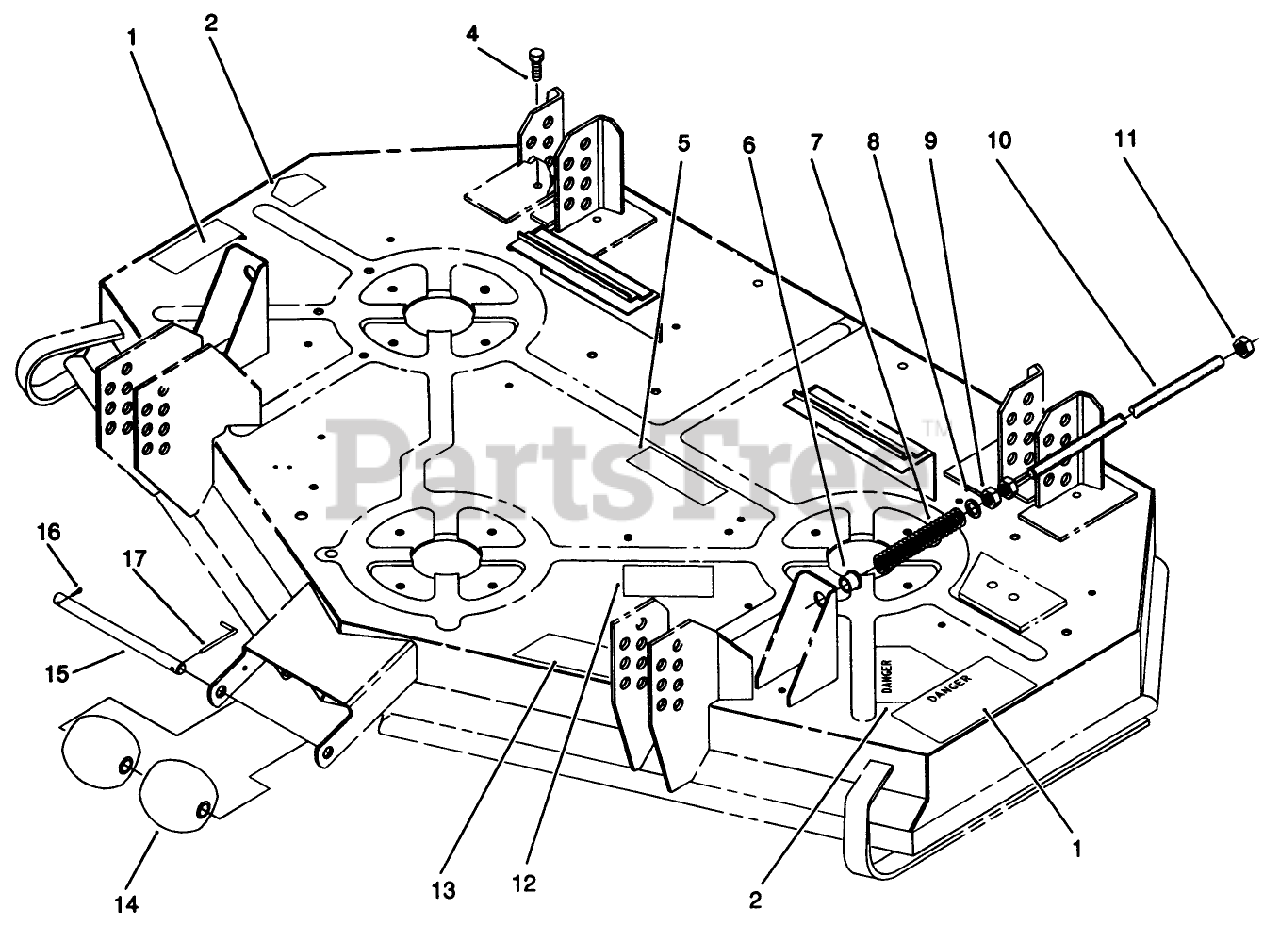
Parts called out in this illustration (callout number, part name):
1	DECAL - DANGER
2	DECAL-DANGER
4	SCREW-HH
5	DECAL - BELT ROUTING
6	BUSHING-FLANGE
7	SPRING
8	WASHER
9	NUT-JAM
10	SHAFT-ADJUSTING
11	NUT-LOCK, NI
12	DECAL-DANGER
13	DECAL-TORQUE
14	ROLLER
15	SHAFT-ROLLER
16	PIN-COTTER
17	PIN-SPECIAL
